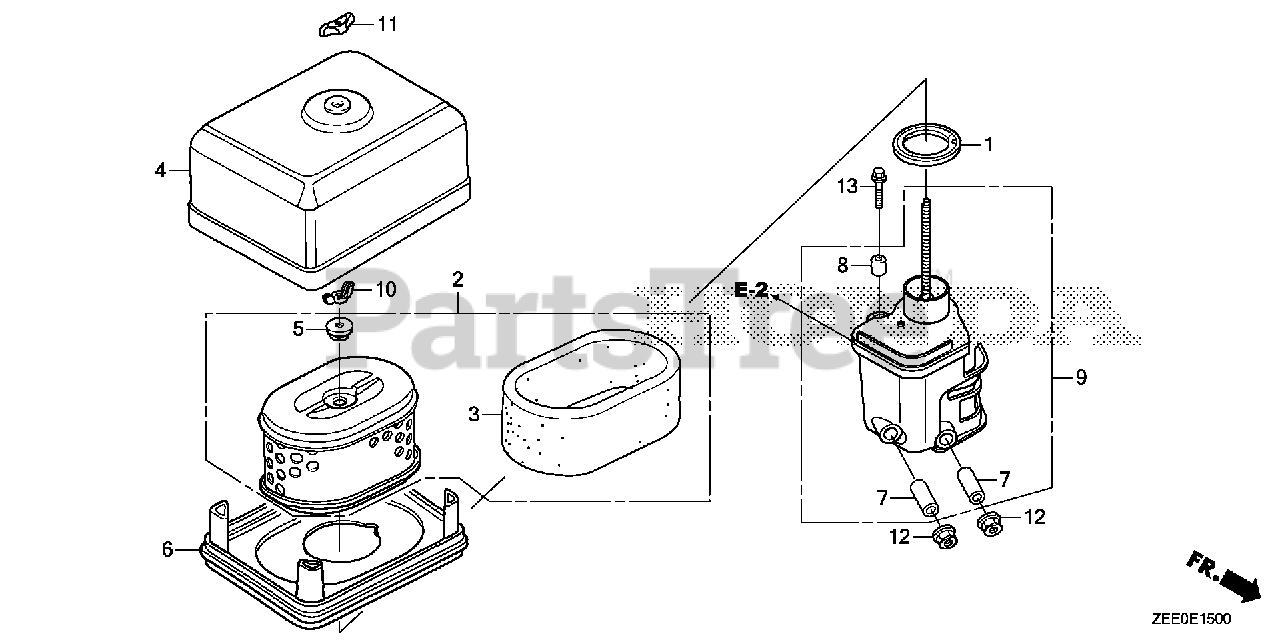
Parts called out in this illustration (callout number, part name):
1	GASKET, ELBOW
2	ELEMENT, AIR CLEANER
3	FILTER (OUTER)
4	COVER, AIR CLEANER
5	GROMMET, AIR CLEANER
6	NOSE, MUFFLER
7	COLLAR, AIR CLEANER Use from Engine SN 1786085.
8	COLLAR B, AIR CLEANER
9	ELBOW, AIR CLEANER
10	NUT, TOOL BOX SETTING (ZHEJIANG HENGBO)
11	NUT, AIR CLEANER
12	NUT, FLANGE (6MM)
13	BOLT, FLANGE (6X20)
